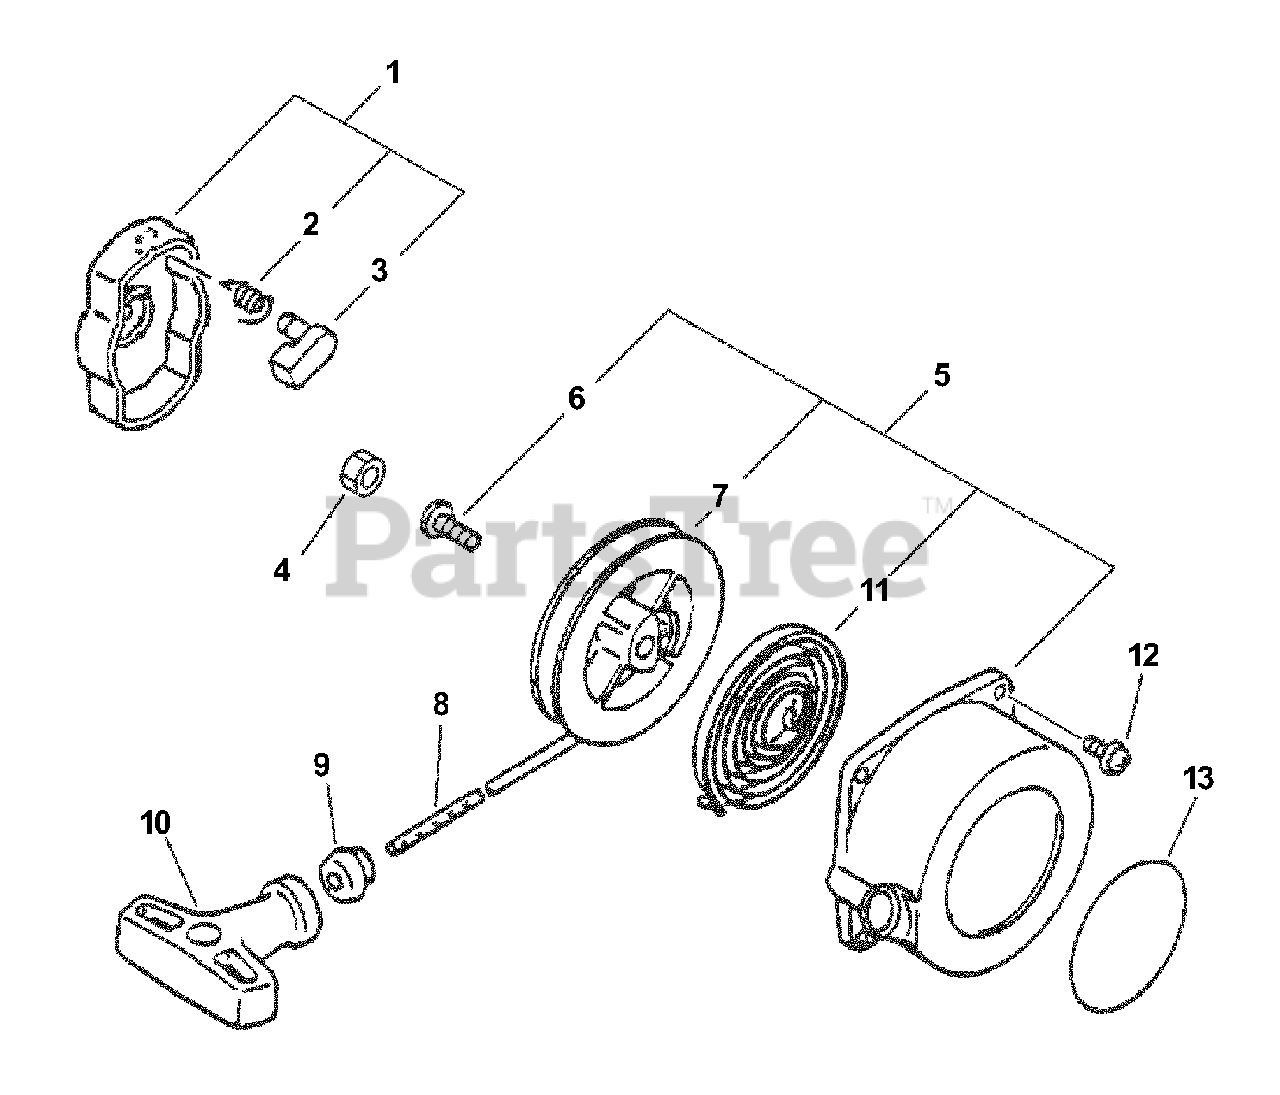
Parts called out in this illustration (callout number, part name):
1	STARTER PAWL ASSY
2	SPRING, RETURN
3	PAWL, STARTER - BLACK
5	STARTER ASSY
7	REEL, ROPE
8	ROPE, STARTER - 3X1000
9	GUIDE, ROPE
10	GRIP, STARTER
11	SPRING, REWIND
12	SCREW - 4X16
13	LABEL - ECHO
